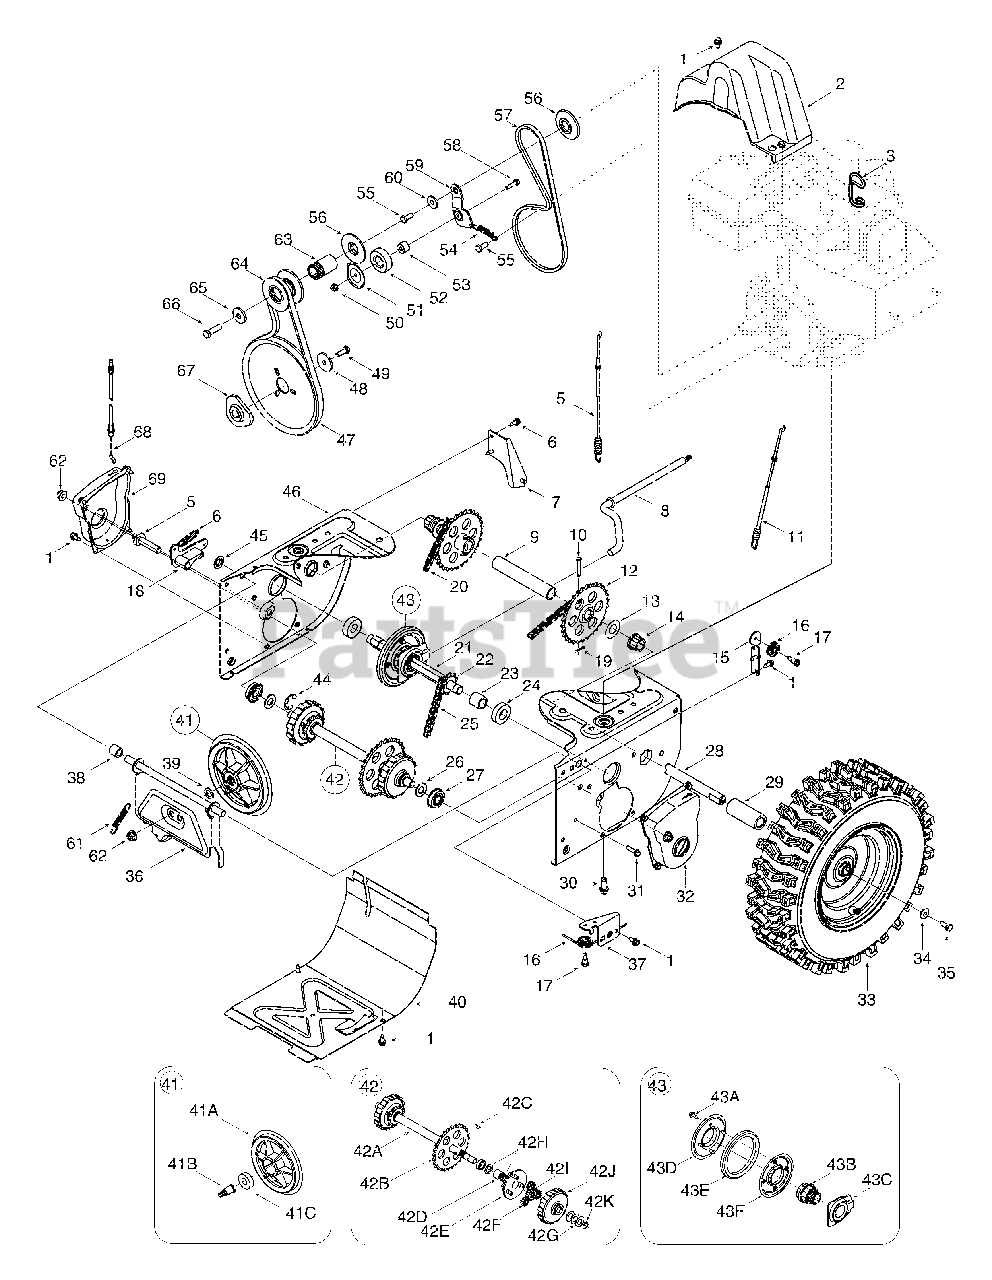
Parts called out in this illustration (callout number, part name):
1	AB Screw, 1/4-20 x 0.625
2	Belt Cover
3	Cable Guide
4	Actuator Shaft
5	Drive Clutch Cable
6	Extension Spring
9	Axle Support Tube
10	Clevis Pin
11	Auger Clutch Cable
12	Sprocket
13	Flat Washer
14	Hex Flange Bearing
17	C Screw, 1/4-28 x 0.375
18	Dogg Assembly - RH
19	Hairpin Clip
20	Chain
21	Drive Shaft
22	Sprocket
23	Spacer
24	Ball Bearing
26	Flat Washer
27	Ball Bearing
28	Axle
29	Spacer
30	TT Sems Screw, 3/8-16 x 1.0
31	TT Screw, 1/4-20 x 1.0
34	Bell Washer
35	Hex Bolt, 5/16-24 x 0.75
38	Spacer
39	Flat Washer
41A	Friction Wheel Disc
41B	Friction Disc Bearing Pin
41C	Ball Bearing
42	Drive Shaft Assembly
42A	Drive Shaft
42B	Sprocket
42D	Spacer
42E	Planetary Carr. Assembly
42F	Gear, 12T
42G	Flat Washer
42H	Flat Washer
42I	Gear,18T
42J	Planetary Ring Gear
42K	Retainer Ring
43	Friction Wheel Assembly
43A	AB Screw, 1/4-20 x 0.625
43B	Friction Wheel Hub
43C	Bearing Assembly
43D	Friction Plate
43E	Friction Wheel Rubber
43F	Friction Plate
44	Retainer Ring
45	Speed Nut
48	Flat Washer
49	Hex Bolt, 5/16-24 x 0.875
50	Flange Lock Nut, 1/4-20
51	Bearing Washer
52	Ball Bearing
53	Spacer
54	Extension Spring
55	Hex Bolt, 5/16-24 x 0.75
56	Pulley Half
57	V-Belt, 3/8 x 28.6
58	Hex Bolt, 1/4-20 x 1.0
61	Extension Spring
62	Jam Nut, 3/8-24
63	Spacer
64	Pulley Half
65	Flat Washer
66	Hex Bolt, 3/8-24 x 1.25
67	Pulley Adapter
68	Steering Cable
69	Shaft Retainer - RH
70	Bell Washer
71	Flange Lock Nut, 3/8-16
72	V-Belt,.500 x 35.00 Lg
73	TT Screw, 5/16-18 x 1.00
